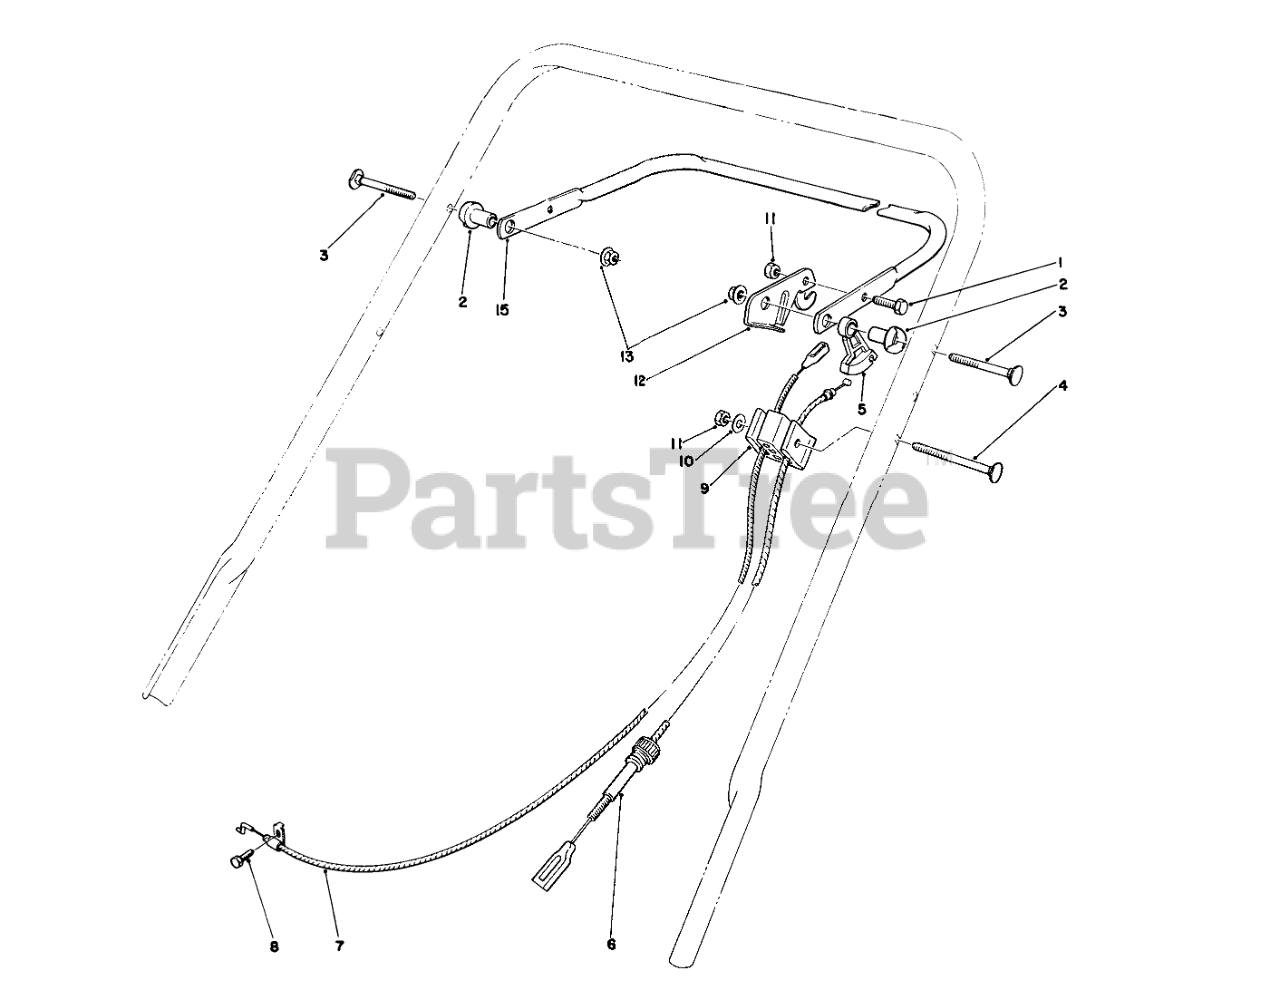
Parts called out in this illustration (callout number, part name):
1	SCREW-HH
2	SPACER-SUPPORT
3	5/16-18 X 2 HNDLE SCREW
4	HANDLE SCREW
5	LEVER-TRACTION
6	CABLE-TRACTION
7	BRAKE CABLE
8	SCREW-HH
9	SUPPORT-CABLE
10	WASHER-FLAT
11	NUT-LOCK, NI
12	LEVER-CONTROL
13	NUT-LOCK, NI
15	Bar-Control
